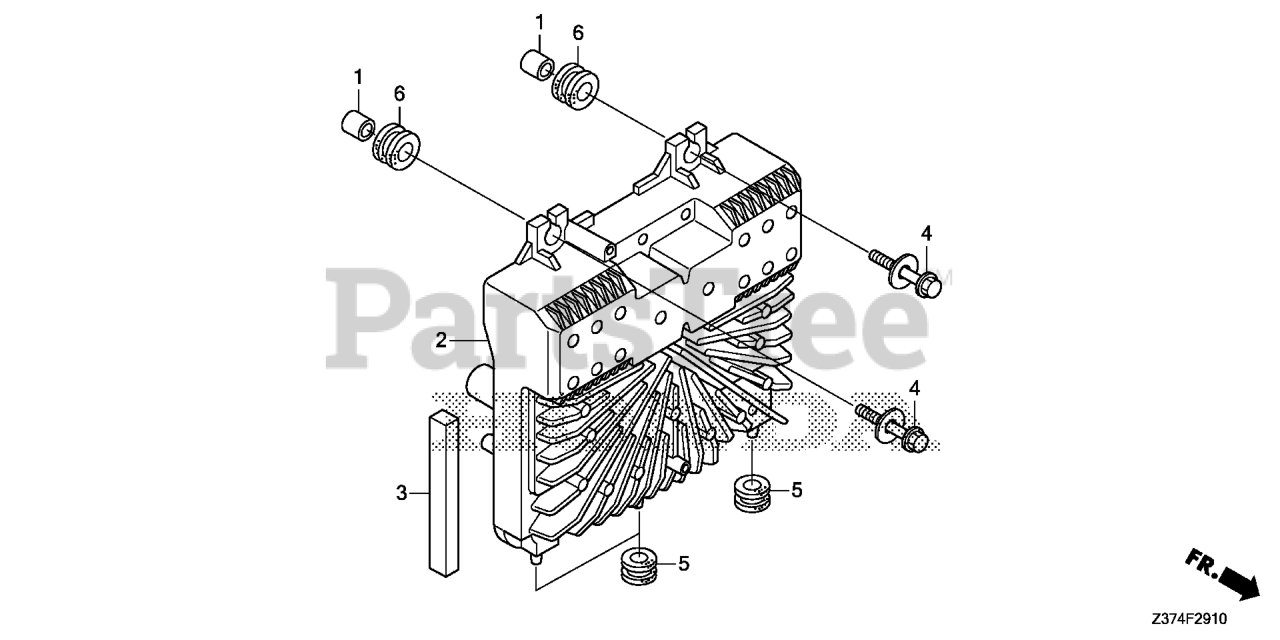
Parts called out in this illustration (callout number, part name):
1	COLLAR, IN. JOINT
2	INVERTER UNIT
3	SEAL (30X22X130)
4	BOLT-WASHER (6X25)
5	RUBBER, TANK CUSHION
6	RUBBER, INVERTER UNIT
